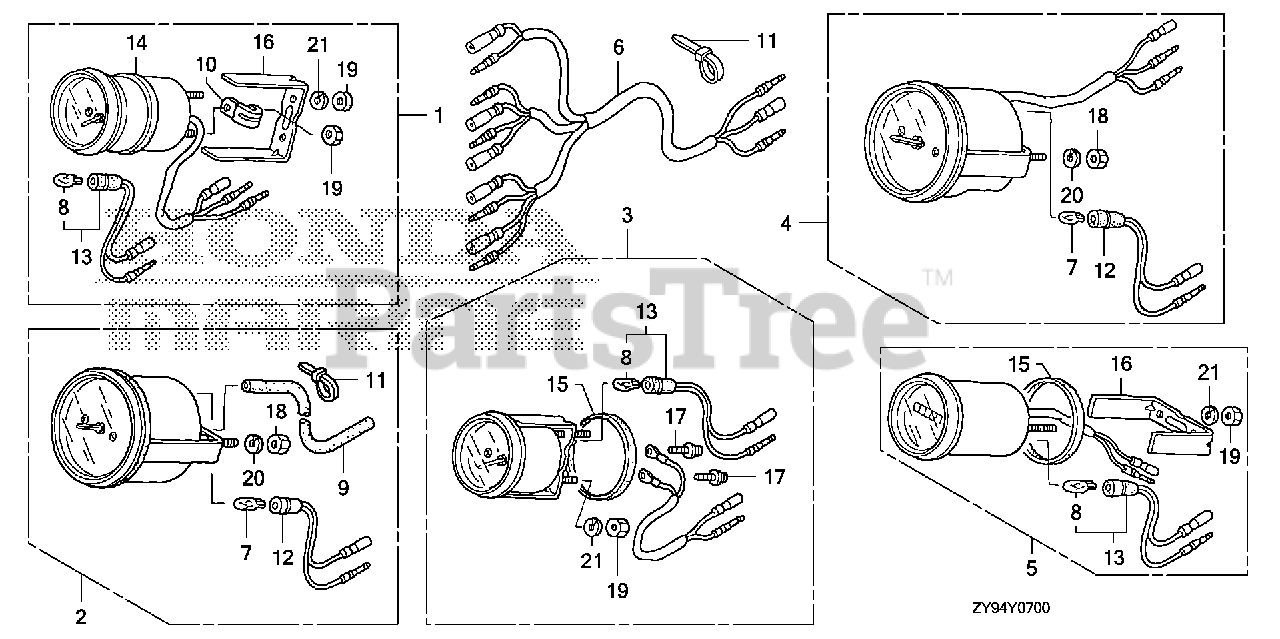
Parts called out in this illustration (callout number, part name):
1	METER KIT, TRIM (WHITE)
1	METER KIT, TRIM (B) (BLACK)
2	SPEEDOMETER KIT (WHITE)
2	SPEEDOMETER KIT *NHA85* (B) (BLACK)
3	METER KIT, VOLT (WHITE)
3	METER KIT, VOLT *NHA85* (B) (BLACK)
4	METER KIT, TACHO
4	METER KIT, TACHO (B)
5	METER KIT, HOUR (WHITE) (NA USE ALT:39700-ZW5-000ZA)
5	METER KIT, HOUR (B) (NA USE ALT:39700-ZW5-000ZA)
6	HARNESS ASSY., METER (B)
7	BULB, WEDGE BASE (T10) (12V 1.7W) (STANLEY)
8	BULB, WEDGE BASE (12V1.7W) (TOSHIBA)
9	TUBE, SPEED METER (4X7X8000)
10	CLAMP
11	BAND, SELF-LOCK
12	SOCKET
13	SOCKET
14	GASKET (TO 1015209) (FROM 1015210)
15	GASKET
16	BRACKET (TO 1015209) (FROM 1015210)
17	SCREW-WASHER (3X22)
18	NUT, HEX. (5MM)
19	NUT, HEX. (4MM)
20	WASHER, SPRING (5MM)
21	WASHER, SPRING (4MM)
